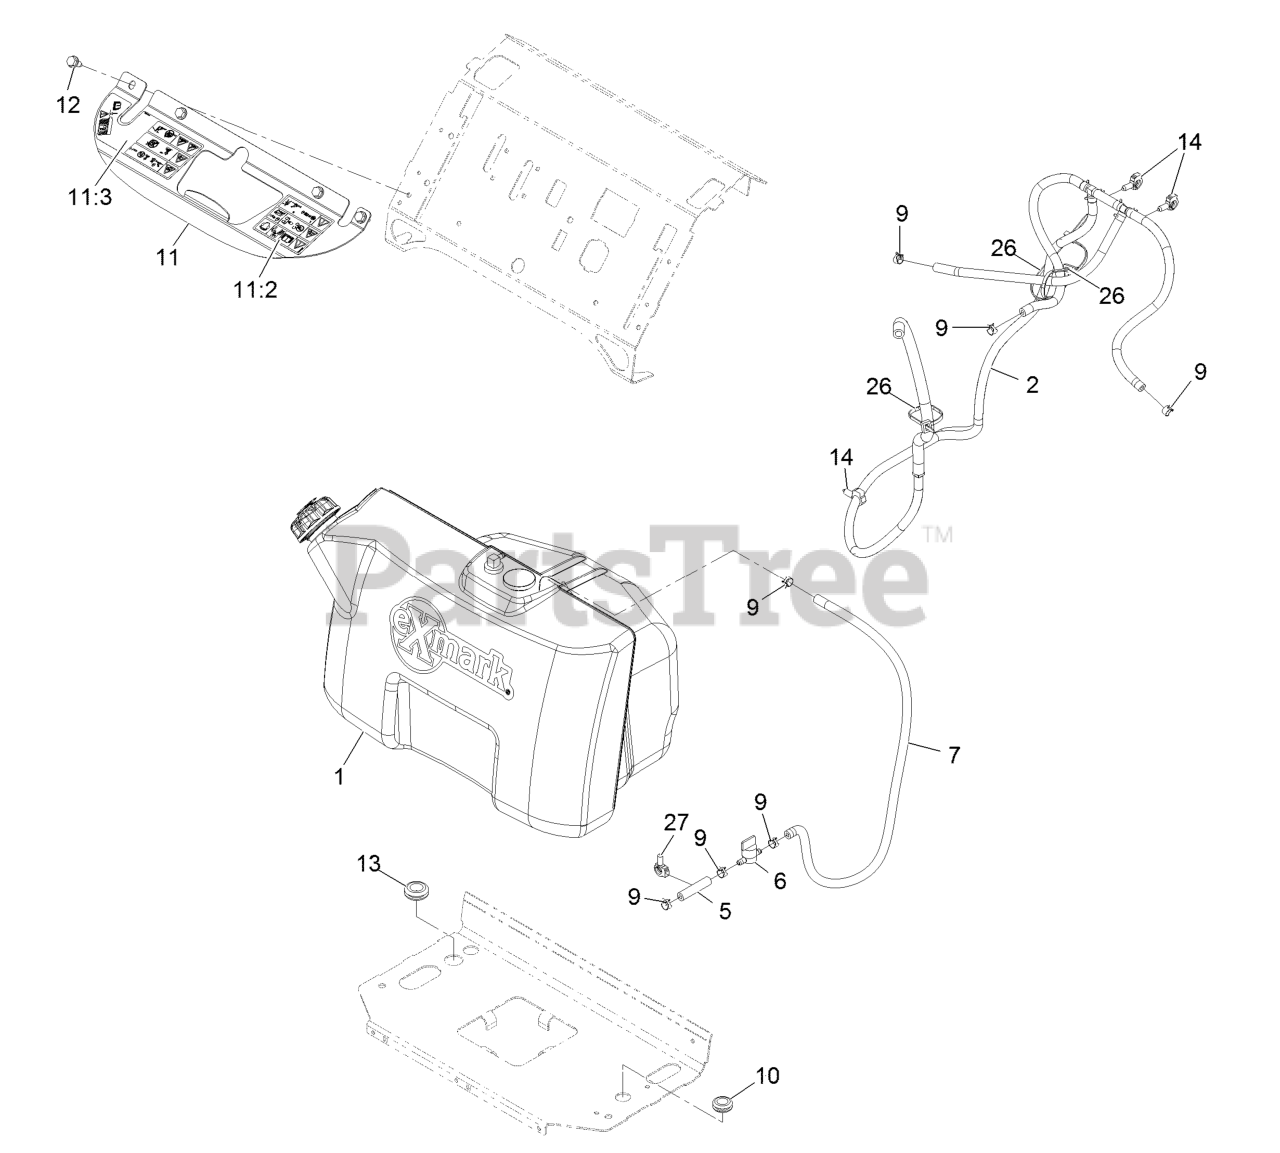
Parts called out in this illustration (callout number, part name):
2	VENT ASM
5	HOSE-FUEL
6	VALVE-FUEL
7	HOSE-FUEL
9	CLAMP-HOSE
10	GROMMET
11	BRACKET-TANK
11:2	DECAL-WARNING LH
11:3	DECAL-WARNING RH
12	Screw-HWH 5/16-18 X 3/4 Tf
13	GROMMET
14	CLIP-HARNESS
26	TIE-CABLE
27	CLIP-HARNESS
